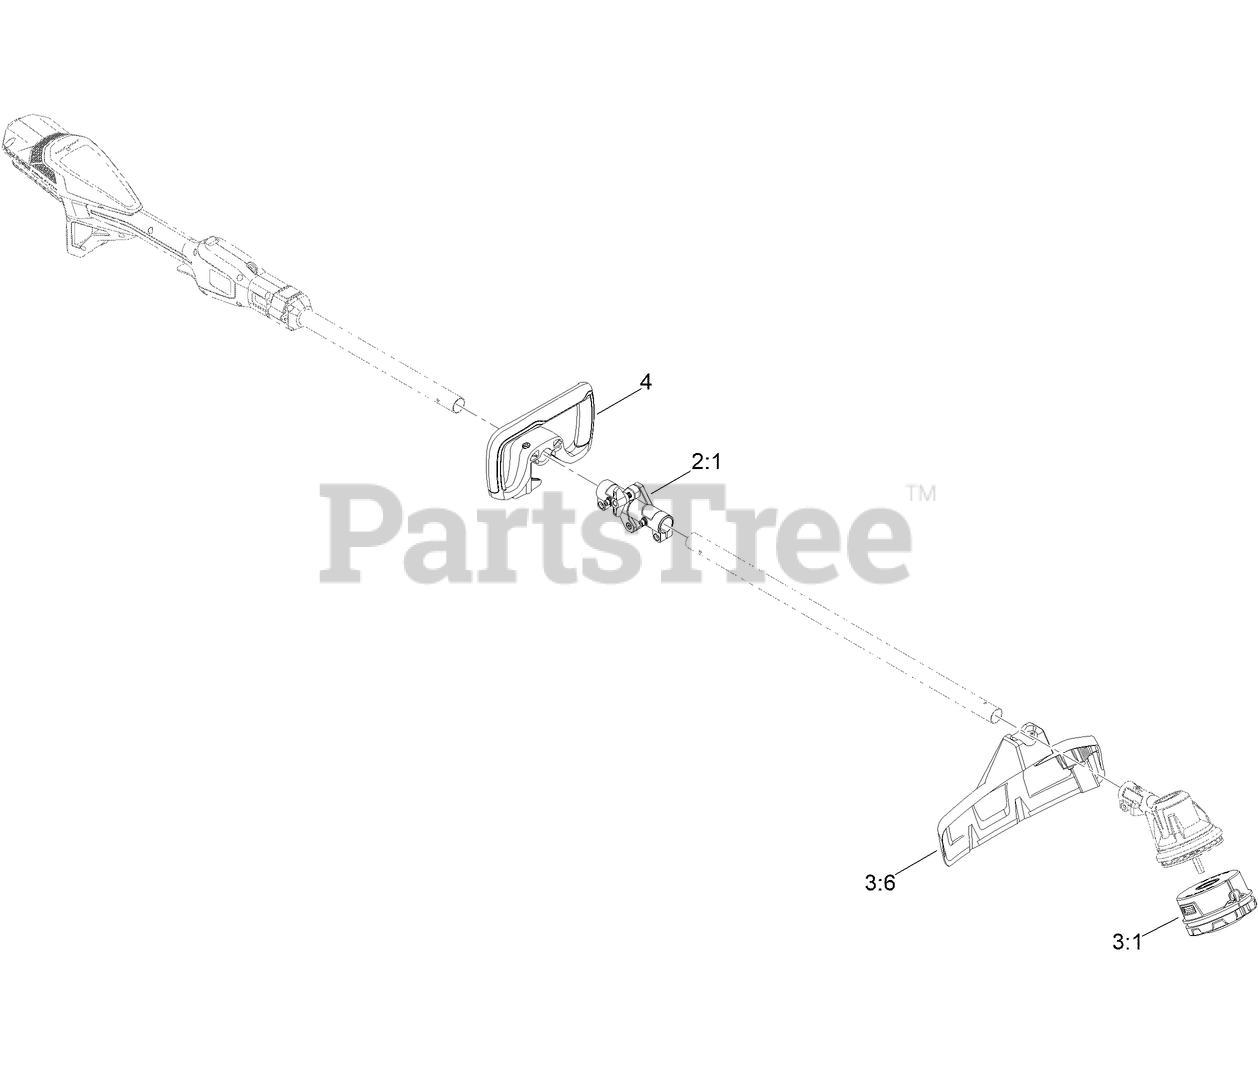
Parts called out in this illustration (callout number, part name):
2:1	60V TRIMMER PIVOT T ASM
3:1	60V TRIMMER BUMP HEAD ASM
3:6	60V TRIMMER GRASS SHIELD ASM
4	60V TRIMMER D-GRIP ASM
